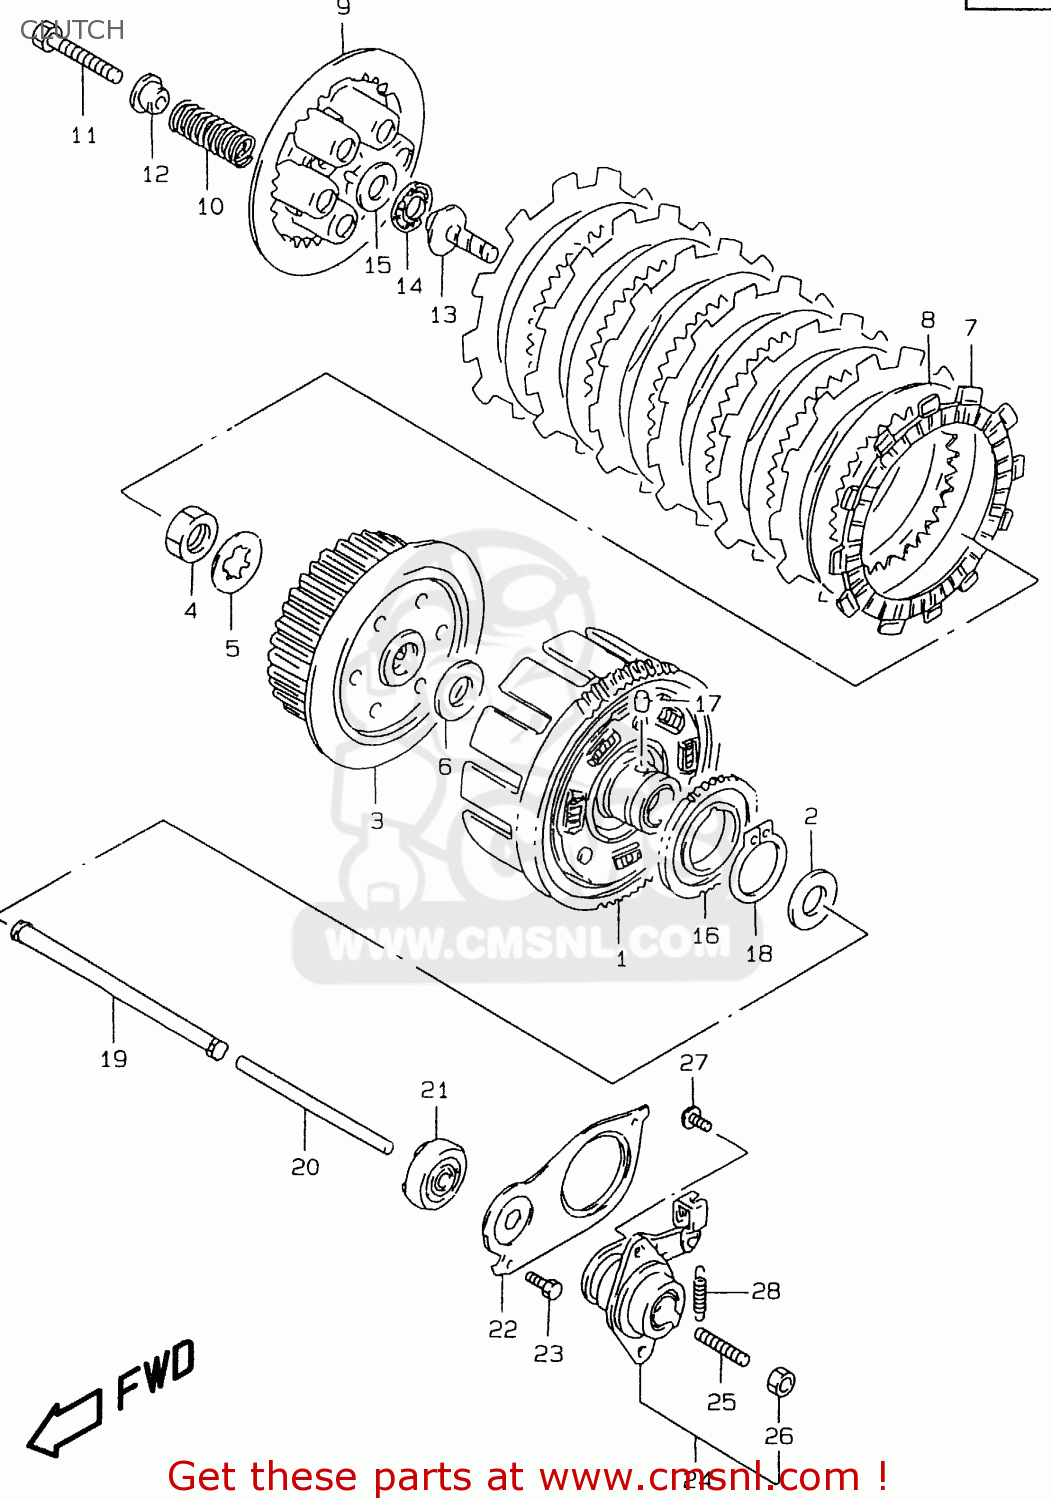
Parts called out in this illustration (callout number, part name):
1	GEAR ASSY,PRI DRIVEN
2	WASHER
3	HUB,CLUTCH SLEEVE
4	NUT
5	WASHER,LOCK
6	WASHER(20X44X3)
7	PLATE,CLUTCH DRIVE (NAS)
8	PLATE,CLUTCH DRIVEN(T:1.6) (NAS)
9	DISC,CLUTCH PRESSURE
10	SPRING
11	BOLT(6X40)
12	SPACER,CLUTCH SLEEVE HUB
13	PIECE,CLUTCH PUSH
14	BEARING(15X28X2)
15	WASHER(15.5X28X1)
16	GEAR,OIL PUMP DRIVE(NT:39)
17	PIN(6X6)
18	CIRCLIP
19	ROD,PUSH,R
20	ROD,CLUTCH PUSH,L
21	SEAL,OIL(6X34X10)
22	RETAINER,PUSH ROD OIL SEAL
23	BOLT
24	SCREW ASSY,CLUTCH RELEASE
25	SCREW(6X25)
26	NUT
27	SCREW 6X16
28	SPRING
